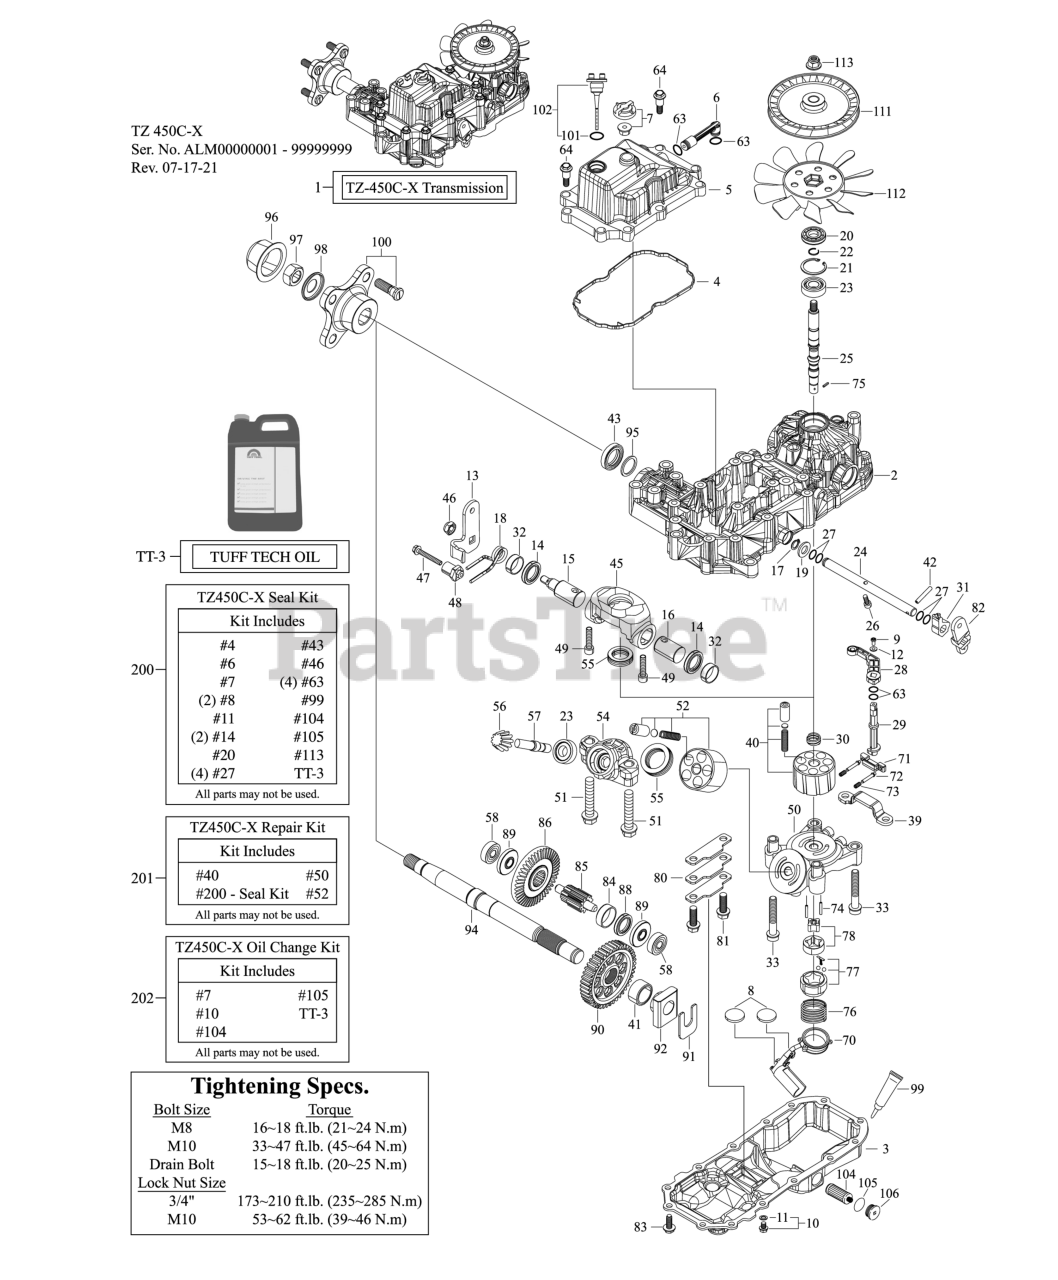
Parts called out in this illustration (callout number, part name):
1	Transaxle - Tuff Torq, LH - SZL
2	Upper Housing X
3	Lower Housing Fy
4	Square Seal
5	Top Cover A
6	Bypass Piping
7	Vent Valve
8	Magnet 28 * 3.5
9	Screw 4.0*8
10	Drain Bolt Kit
11	Washer Seal 10
12	Washer 4.5*10*1
13	Control Lever L
14	Seal, Tc253506
15	Control Shaft
16	Control Shaft Short
17	Snap Ring
18	Torsion Spring
19	Washer 12
20	Oil Seal 15*35*07
21	Snap Ring C 35
24	Brake Shaft
25	Pump Shaft C
26	Socket Bolt 6*16
27	O-Ring 1a P12
28	Bypass Lever
29	Bypass Shaft
30	Pump Spring
31	Brake Fork 20 Cr
32	Control Bush Lfb2510
33	M10 * 65 Bolt
39	Check Stopper Pfg
40	Cylinder Block Kit / Order Repair Kit
41	Bushing 25.4
42	Spring Pin 5 * 32
43	Seal Tc284008
45	Swashplate
46	Lock Nut 10
47	Bolt 6*45
49	Bolt 8 * 35
50	Centercase Cp / Order Repair Kit
51	Bolt 12*65
52	Cylinder Block Kit(Motor / Order Repair Kit
54	Motor Housing
55	Thrust Bearing
56	Motor Gear S
57	Motor Shaft
58	Bearing 6201 Cn
63	0-Ring 1a P10a
64	Tapping Bolt 8*30
70	Bracket Assy Fts
71	Bypass Guide
72	Bypass Pin
73	Bypass Spring
74	Pin 3.0 * 18
75	Pin 2.5* 9.8
76	Charge Spring
77	Pump Case
78	Rotor Set
80	Final Plate
81	Bolt 10 * 30
82	Brake Arm
83	Tapping Screw 8 * 20
84	Final Pinion Collar
85	Final Pinion Shaft
86	Reduction Gear S
88	Reduction Collar
89	Reduction Collar
90	Final Gear Sv
92	Bushing 25.4
94	Axle Shaft T
96	Nut Cap
97	Lock Nut 3/4-16
98	Flange Spacer
100	Flange Assy.
101	O-Ring 1a P16
102	Dipstick Assy.
104	Filter
105	O-Ring 1a 24040
106	Cap 40
111	Pulley,5.5
112	Fan
113	Lock Nut 10
200	Seal Kit Tz-450
201	Repair Kit Tz-450 C
202	Tz 450 Oil Change Kit
TT-3	Tuff Tech Oil (3 Liter Bottle)
